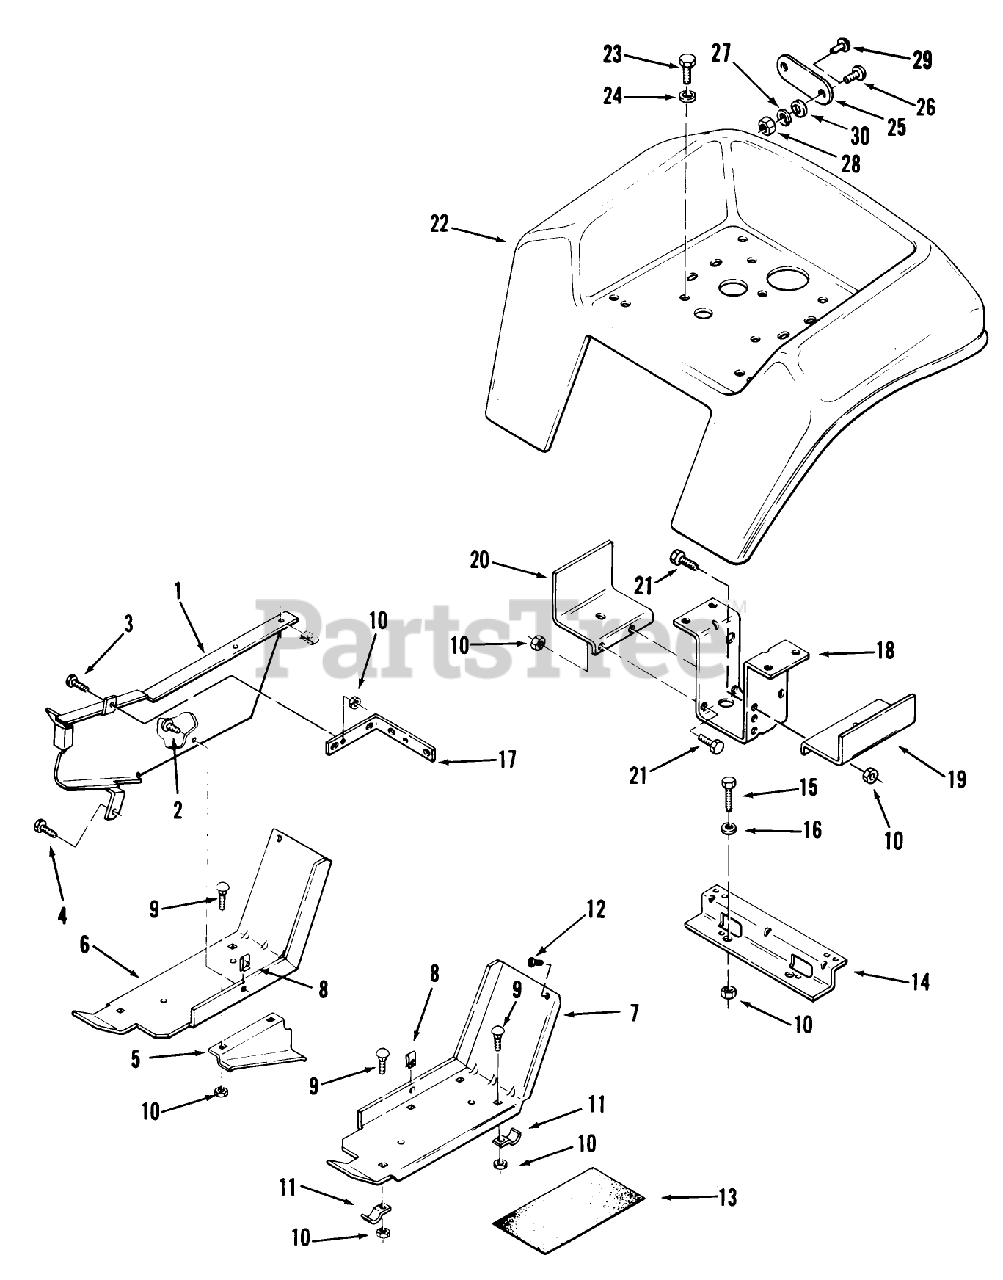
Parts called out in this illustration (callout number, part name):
4	SCREW
7	FOOTREST LH *R
9	CARRIAGE BOLT -4
11	BRACKET
12	BUMPER-RUBBER
13	PAD-FOOTREST
16	WASHER 5/16 SAE
17	BRACKET-BELT*B
24	WASHER 5/16 SAE
30	WASHER
